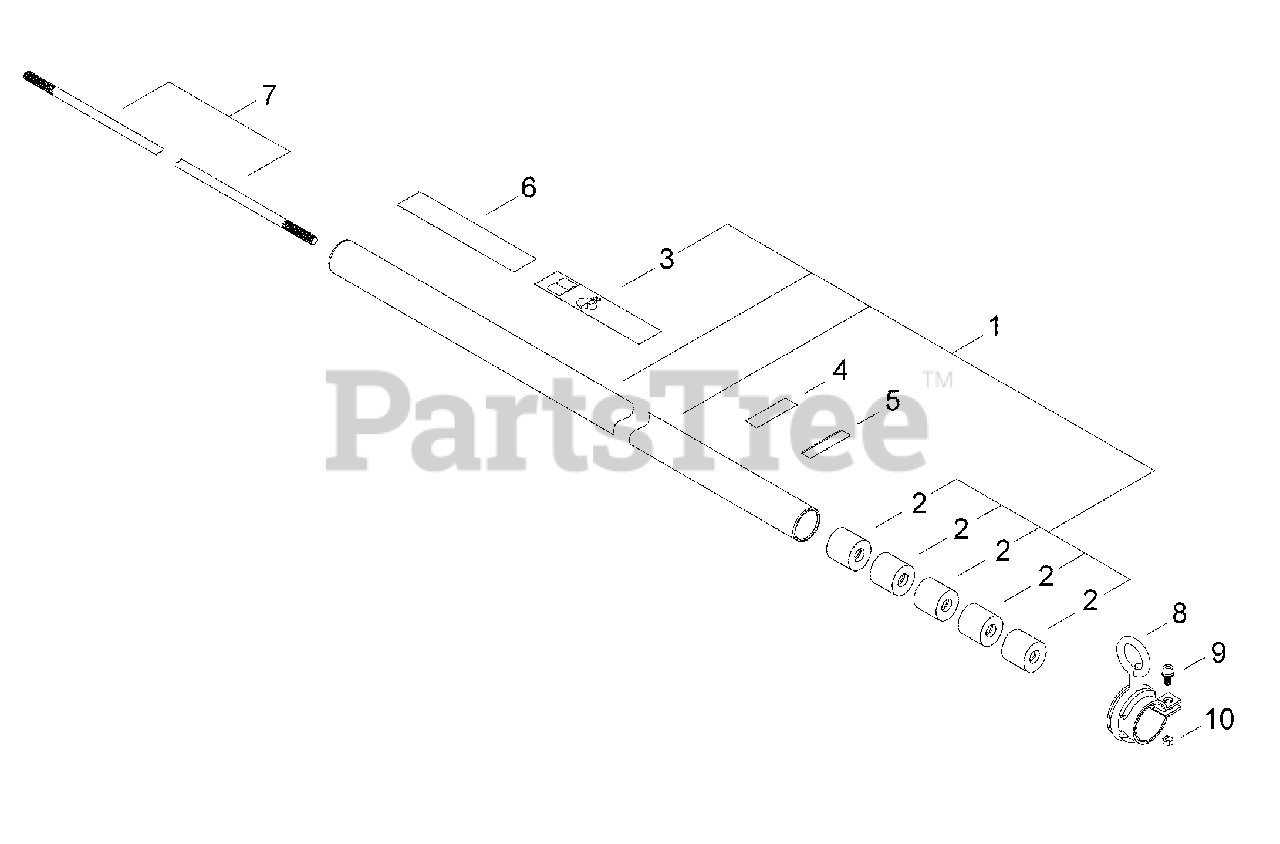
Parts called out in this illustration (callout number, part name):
1	OUTER TUBE ASSY
2	BUSHING
3	LABEL - CAUTION
4	LABEL - INSTRUCTION
5	LABEL - HANDLE LOCATION
6	LABEL - SWISHER E4
7	PIPE, MAIN
8	HANGER
9	SCREW - 5X12
